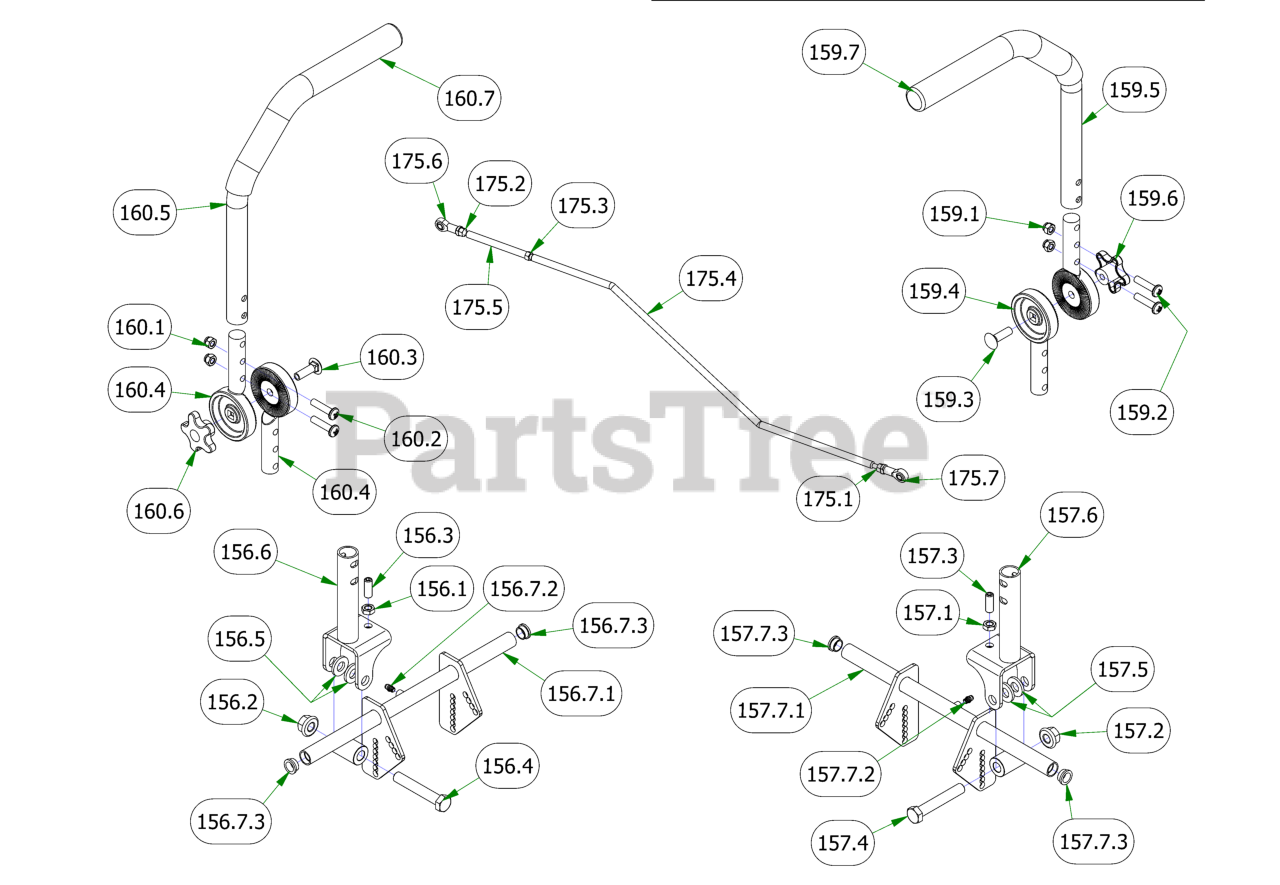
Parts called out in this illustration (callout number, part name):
156	2019 R Series RH Arm Rod Assembly
156.1	3/8-16 Half Jam Nut
156.2	1/2-13 NYLON INSERT FLANGE LOCKNUT ZINC
156.3	3/8-16 X 1 SOCKET SET SCREW (CUP POINT) PLAIN
156.4	1/2-13 X 3 HEX CAP SCREW (GR.5) ZINC
156.5	.505 ID X 1.000 OD X .125 THICK FLAT WASHER NYLON
156.6	Drive Arm Pivot
156.7	2019 Drive Arm Actuator right
156.7.1	2019 Drive Arm Actuator right - Weldment
156.7.2	1/4" Press in Grease Fitting
156.7.3	2019 Drive Arm Bushing
157	2019 R Series LH Arm Rod Assembly
157.1	3/8-16 Half Jam Nut
157.2	1/2-13 NYLON INSERT FLANGE LOCKNUT ZINC
157.3	3/8-16 X 1 SOCKET SET SCREW (CUP POINT) PLAIN
157.4	1/2-13 X 3 HEX CAP SCREW (GR.5) ZINC
157.5	.505 ID X 1.000 OD X .125 THICK FLAT WASHER NYLON
157.6	Drive Arm Pivot
157.7	2019 Drive Arm Actuator left
157.7.1	2019 Drive Arm Actuator left - Weldment
157.7.2	1/4" Press in Grease Fitting
157.7.3	2019 Drive Arm Bushing
159	2019 Left Hand ADJ. Steering Arm Kit
159.1	5/16-18 NYL INS L/N ZC
159.2	5/16-18 x 1 3/8" Futton Head Torx Drive Bolt
159.3	3/8-16 X 1-1/4 CARRIAGE BOLT ZINC
159.4	2019 Steering Arm Adjuster Casting
159.5	2019 Steering Arm Tube
159.6	Black Knob for Adjustable Steering Arm
159.7	Black Steering Arm Grip
160	2019 Right Hand ADJ. Steering Arm Kit
160.1	5/16-18 NYL INS L/N ZC
160.2	5/16-18 x 1 3/8" Futton Head Torx Drive Bolt
160.3	3/8-16 X 1-1/4 CARRIAGE BOLT ZINC
160.4	2019 Steering Arm Adjuster Casting
160.5	2019 Steering Arm Tube
160.6	Black Knob for Adjustable Steering Arm
160.7	Black Steering Arm Grip
175	2019 Renegade Push Rod Assembly
175.1	5/16" RH Fine Threaded Jam Nut
175.2	5/16" LH Fine Threaded Jam Nut
175.3	3/8" Fine Threaded Jam Nut
175.4	2019 Renegade Push Rod
175.5	2019 Renegade Push Rod Adjuster
175.6	Spherical Rod End - Outlaw
175.7	Spherical Rod End - Outlaw
